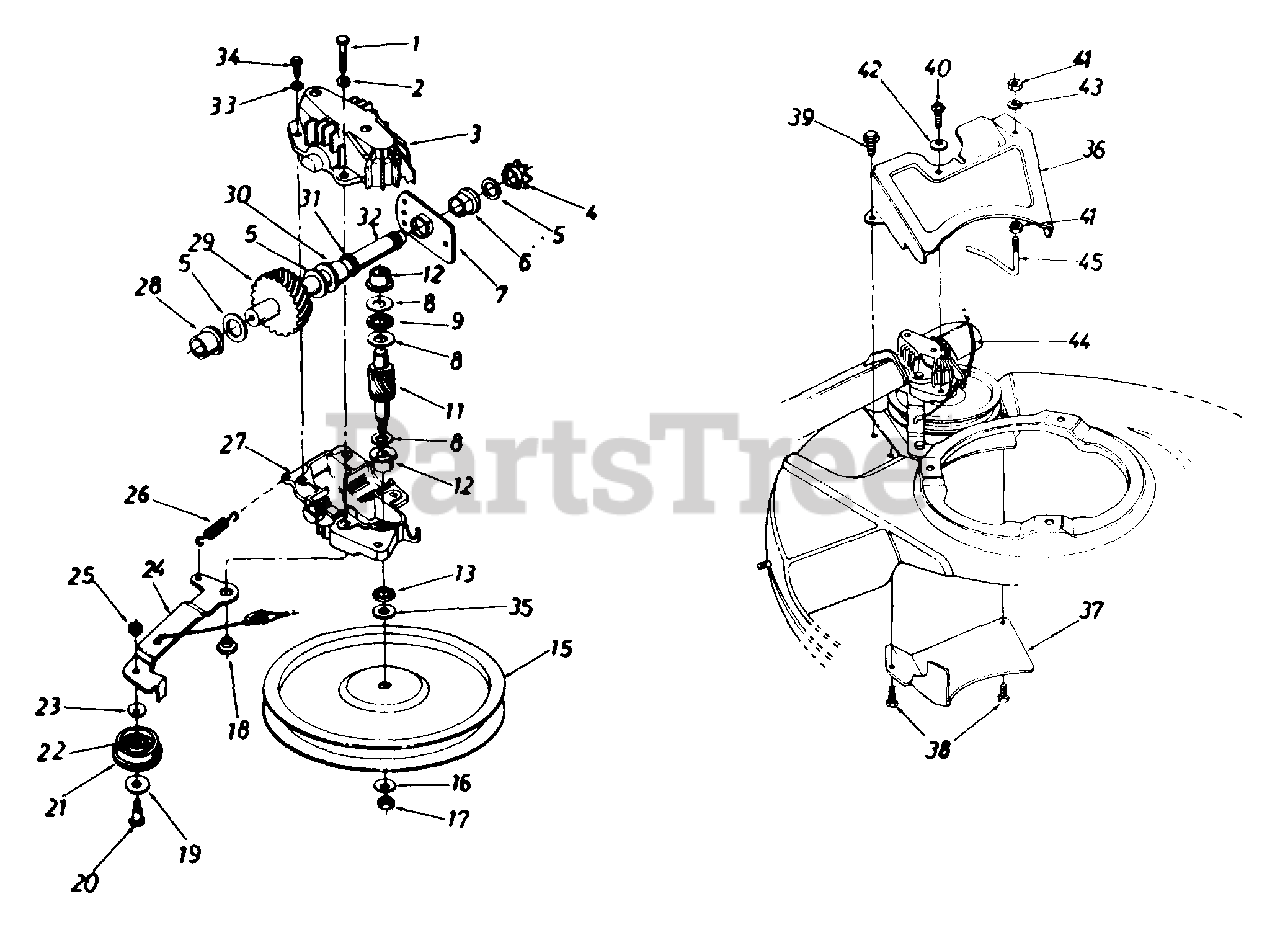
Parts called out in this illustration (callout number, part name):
1	Hex Bolt 1/4-20 x 1.25" Lg. w/Patch
2	L-Wash. 1/4" I.D.
3	Upper Hsg. Half
4	#48 Sprocket 7 Tooth x 1/2 Pitch
5	Fl-Wash. 5/8" I.D. x .030
6	Hex Flange Brg..631" I.D.
7	Hex Bearing Cup
8	Thrust Wash..382" I.D. x .70" O.D.
9	Thrust Bearing .375" I.D. x .812" O.D.
11	11 Tooth Helical Gear
12	Flange Bearing
13	Oil Seal
15	Fl-Pulley 5.06" I.D.
16	Bell-Wash..265" I.D. x .75"
17	Hex Nut 1/4-28 L.H. Thd.
18	Shld. Spacer .375" Dia. x .170"
19	Fl-Wash..390" I.D. x 1.0"
20	Shld. Bolt .375" Dia. x .40"
21	Fl-Idler Plastic 1.50" Dia.
22	Needle Brg..375" x .31"
23	Bell-Wash..265" I.D. x .75"
24	Idler Brk't. Ass'y.
25	Hex Patch L-Nut 1/4-28 Thd.
26	Extension Spring 1.12" Lg.
27	Lower Hsg. Half
28	Flange Bearing .56 Dia.
29	33 Tooth Helical Gear
30	Flange Bearing .629 Dia.
31	Oil Seal .625 Dia.
32	Gear Sprocket Shaft
33	L-Wash. #10 I.D.
34	Hex B-Tap Scr. #10 x .62"
35	Hex Washer .26" x .88"
39	Hex AB-Tap Scr. 1/4 x .50" Lg.
40	Hex B-Tap Scr. 1/4 x .62" Lg.
41	Hex Nut 1/4-20 Thd.
42	Bell-Wash..265" I.D. x .75"
43	L-Wash. 1/4" I.D.
44	S.P. Cable - 48" Lg.
45	S.P. Belt Guard)
